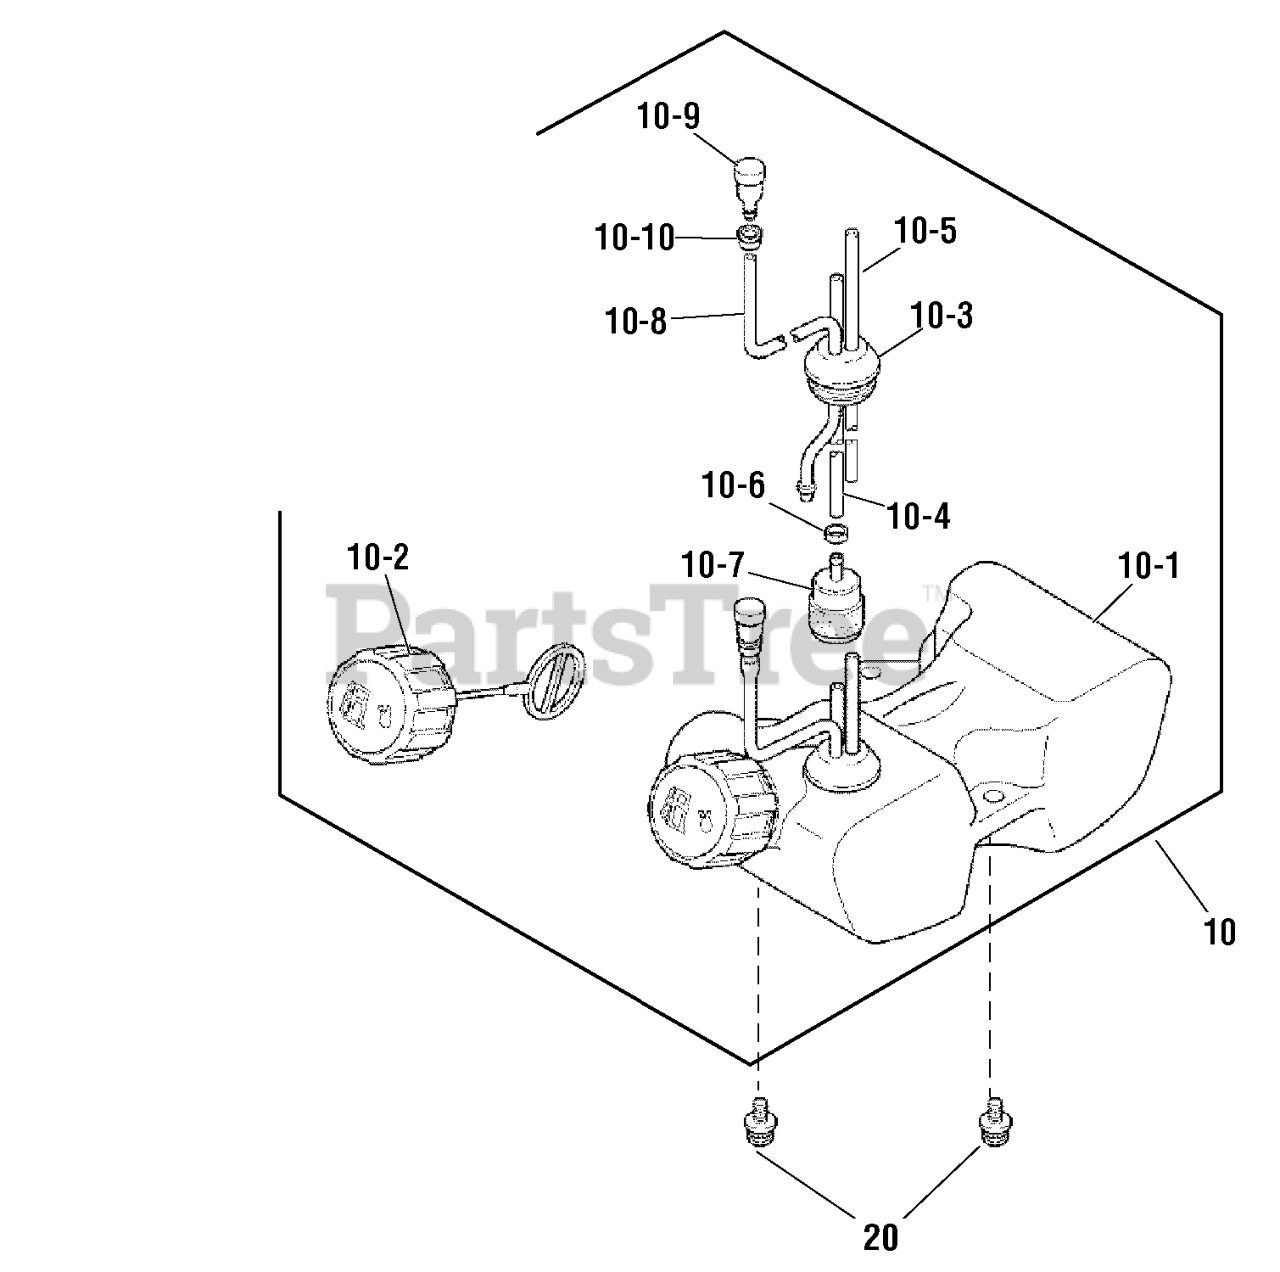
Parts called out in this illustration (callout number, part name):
10	FUEL TANK ASSEMBLY
10-1	FUEL TANK
10-2	FUEL CAP
10-3	GROMMET
10-4	TUBE, Fuel
10-5	TUBE, Fuel
10-6	BUSH
10-7	FILTER, Fuel
10-8	HOSE, Fuel
10-9	VALVE, Breather
10-10	CLIP
20	SCREW & WASHER
